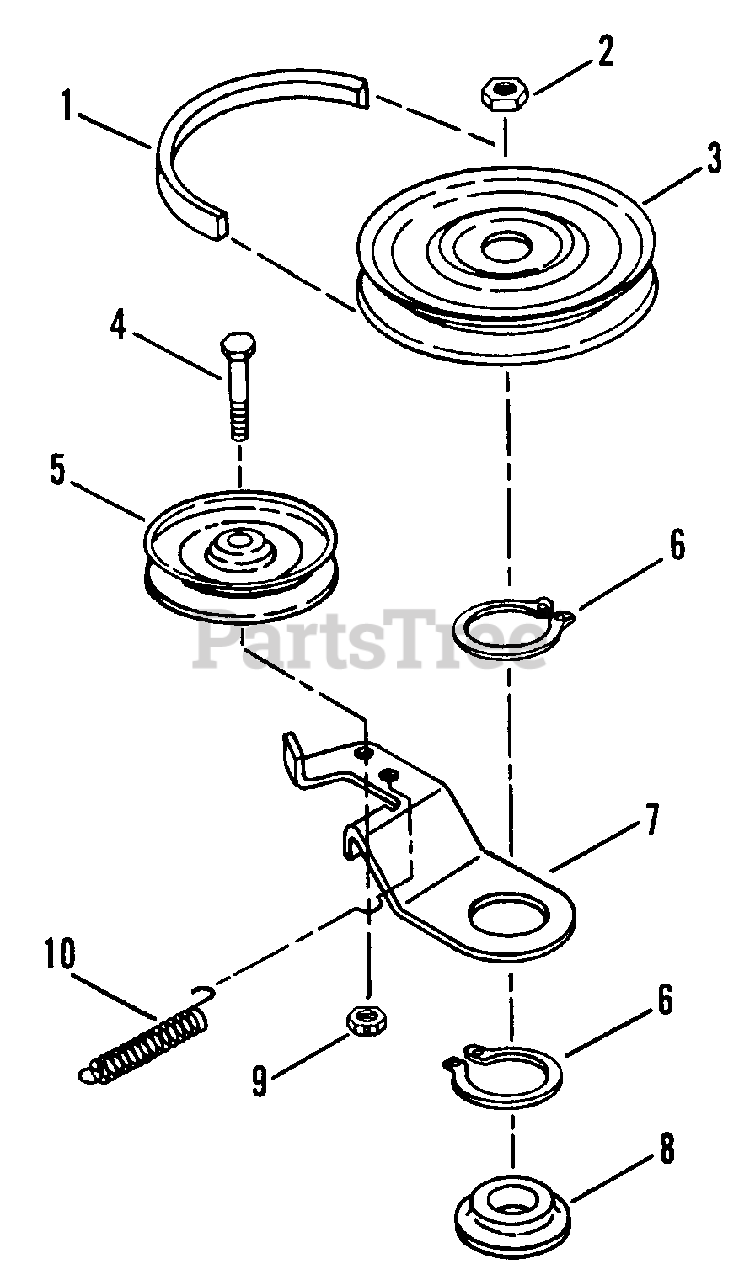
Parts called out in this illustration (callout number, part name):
1	BELT, Drive
2	NUT, 3/4-16 Hex Jam
3	PULLEY, Drive
4	SCREW, 3/8-16 x 2" Hex Head Cap, Grade 5
5	PULLEY, Idler
6	RING, 2" External Retaining
7	ARM, Brake
8	WASHER, Spindle
9	NUT, 3/8-16 Hex Center Lock, Grade 5 or B
10	SPRING, Idler
